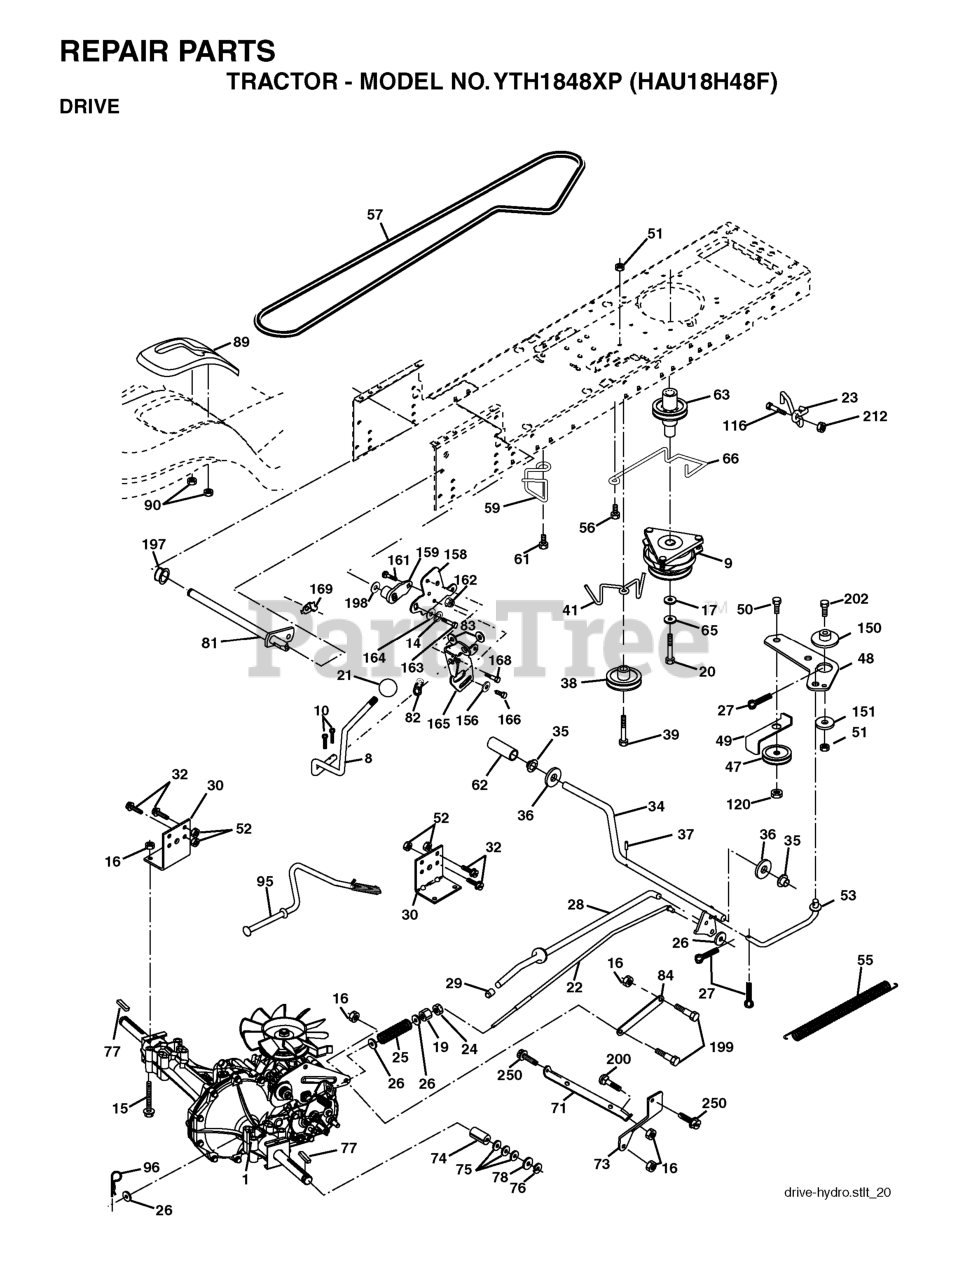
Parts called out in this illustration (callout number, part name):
8	ROD SHIFT FENDER ADJUST STLT
9	CLUTCH ELECTRIC
10	PIN COTTER
14	LOCKWASHER
15	BOLT HEX 5/16-18 GR 5
16	NUT.71038.31-18.HEX.NYLOCK
19	NUT
20	BOLT HEX 7/16-20X4-1/4"
21	KNOB.DELUXE.(PISTOL.GRIP).BLAC
22	ROD BRAKE HYDRO
23	BRKT ASM MTNG
24	NUT
25	SPRING ROD LT
26	WASHER
27	COTTER PIN
28	ROD, PARKING BRAKE
29	PLUNGER CAP
30	BRKT, TRNSXLE MNT 20"
32	BOLT
34	SHAFT, FOOT PEDAL
35	BEARING.NYLON
37	DRIVE PIN
38	PULLEY IDLER COMPOSITE
39	BOLT
41	KEEPER, BELT IDLER
47	IDLER PULLEY
48	BELLCRANK, CLUTCH
49	RETAIN BELT
50	BOLT.3/8-16X1.50
52	LOCKNUT
53	LINK, CLUTCH LT
55	SPRING, RETURN LT
56	SCREW.3/8-16
57	DRIVE BELT, LTH & YTH TRACTORS
59	KEEPER, BELT CENTER
61	SCREW 3/8-16X.875
62	PEDAL COVER T
63	PULLEY- ENGINE
65	LOCKWASHER
66	KEEPER BELT ENGINE
71	STRAP TORQUE LH HYDRO
73	STRAP TORQUE RH HYDRO
74	SPACER AXLE
77	SQUARE KEY
81	SHAFT ASM CROSS TAPERED
82	SHIFT SPRING
83	WASHER
84	LINK TRANSAXLE
89	SHIFT CONSOLE
90	NUT.PUSH.3/16
95	CONTROL ASM. BYPASS HYDRO
96	RETAINER M
116	BOLT D
120	NUT LOCK FLG 3/8-16 UNC
150	SPACER, RETAINER
151	WASHER 12/32X2X10GA
156	WASHER.SRRTD.5/16
158	BRACKET
159	RB HUB.SHIFT
161	BOLT
162	NUT.CROWNLOCK.1/4
164	Washer 5/8 x .281 x 10 Ga.
165	RP BRACKET
168	BOLT.SHOULDER.5/16-18X
169	PLATE.FASTENING.CROSS.SHAFT
197	NYLINER SNAP 5/8" ID
198	WASHER.NYL.7/8IDX.105"HYD CR
199	BOLT SHOULDER 5/16-18 UNC
212	NUT
250	SCREW, 3/8-16X3/4
